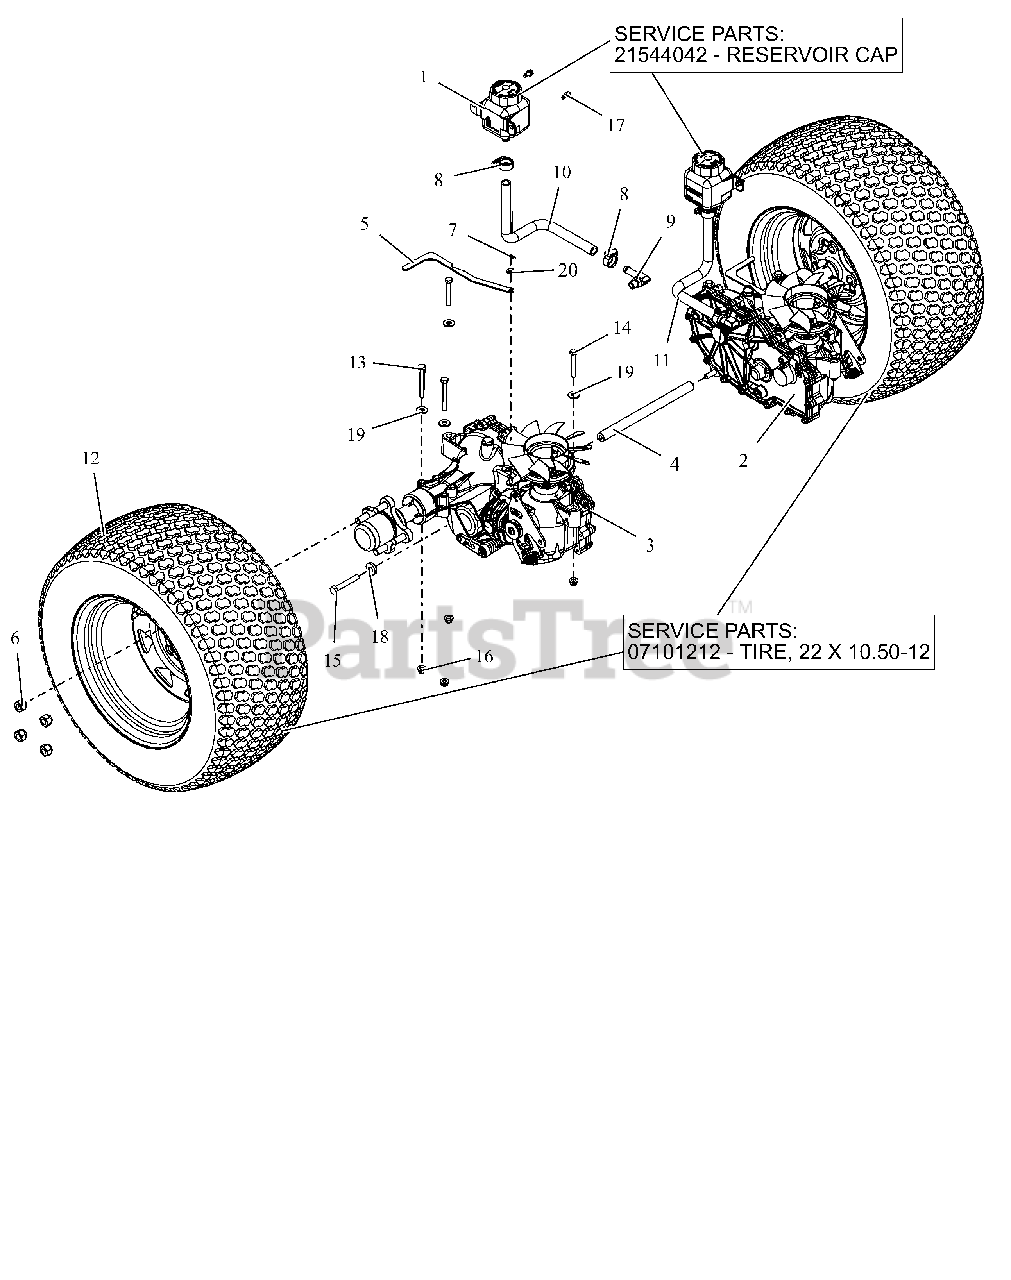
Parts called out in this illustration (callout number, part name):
1	TANK, EXPANSION
1	CAP, HYDRO RESERVOIR REPLAC.
2	TRANSAXLE, ZT3100 LH
3	TRANSAXLE, ZT3100 RH
4	SHAFT, TRANSAXLE SUPPORT
5	BRKT, VALVE DUM
6	NUT, WHEEL .50-20 ZCC
7	PIN, HAIR #225 .072X1.09
8	CLAMP,.88 DIA. HOSE
9	FITTING, HYD (90 DEG)
10	HOSE, FORMED EXPANSION -HD RH
11	HOSE, FORMED EXPANSION -HD LH
12	ASM, WHL/TIRE 22X10.50-12 K500
12	TIRE, 22X10.50-12
13	BLT, HEX .31-18X2.75 G5 ZCC
14	BLT, HEX .31-18X2.25 G5 ZCC
15	BLT, HEX .38-16X2.50 G5 ZCC
16	NUT,NYL-FLG .31-18 GF ZCC
17	SCR-TAP .25-20X.50 HWH ZCC
18	WSHR, FLT .406X1.00X.188 ZCC
19	WSHR,FLT .375X.875X.083 ZCC
20	WSHR,FLT .281X.625X.065 ZCC
